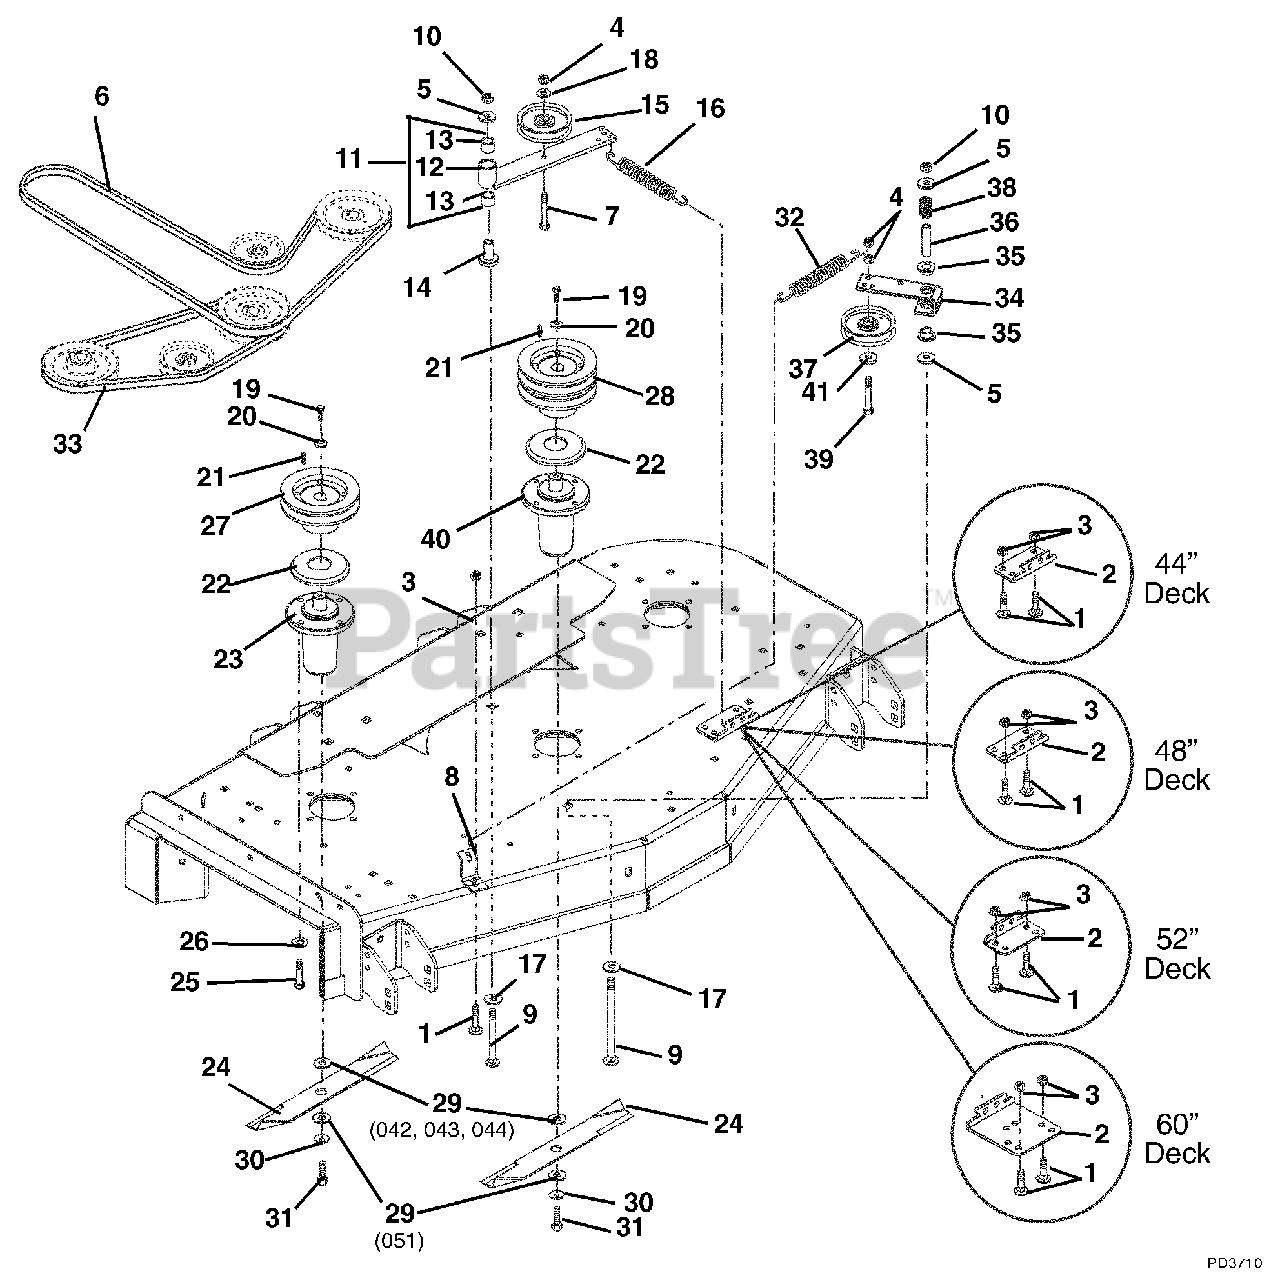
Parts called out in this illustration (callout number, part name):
1	Bolt-Round Head Square Neck .38-16 x .75 Grade 5 (042, 043, 044, 054, 310, 311)
1	Bolt-Round Head Square Neck .38-16 x 1.25 Grade 2 (051, 055)
2	Bracket, Spring (042, 043, 044, 054 310, 311)
2	Bracket, Spring (051, 055)
3	Nut-Locking-Top-Flange .38-16
4	Nut-Locking-Center .38-16
5	Washer-Flat-Steel .531 x 1.25 x .10
6	V-Belt B-Section 51.50 x .625 (042, 044, 054, 310)
6	V-Belt, B-Section 48.80 x .625 (043, 311)
6	V-Belt, B-Section 55.75 x .625 (051, 055)
7	Bolt-Hex .38-16 x 2.75 Grade 5
8	Anchor, Spring
9	Bolt-Round Head Square Neck .50-13 x 3.50 Grade 5
10	Nut-Locking-Top-Flange .50-13
11	Assembly, Idler Pivot Arm (Contains Items 12 & 13)
12	Weldment, Idler Pivot Arm
13	Bearing, 1.00 x 1.12 x .75
14	Bearing, Pedestal Powdered Metal
15	Idler-Flat 4.00 x .38 (2.00 W)
16	Spring-External .09 x 1.00 x 6.00
17	Washer-Flat-Steel .755 x 1.375 x .062 (042, 043, 044, 054, 055, 310, 311)
18	Washer-Flat-Steel .375 x 1.125 x .065
19	Bolt-Hex .38-16 x 1.00 Grade 8
20	Washer-Cupped-Serrated .375
21	Key-Straight .25 x 1.00 x .25
22	Slinger-Dust
23	Assembly, Maintenance Free Spindle
24	Blade- Mower (042, 043)
24	Blade, 32" (16.25) (310, 311)
24	Blade- Mower (18.00) (044, 054)
24	Blade, Mower 60" (051, 055)
24	Blade- Mulching (042, 043)
24	Blade- Mulching (18.00) (044, 054)
24	Blade, Mower 60" Tungsten Mulch (051, 055)
25	Bolt-Hex .38-16 x 1.00 Grade 5
26	Washer-Locking .38 x .094 Regular
27	Weldment, Spindle Sheave 5.00 (042, 043, 044, 054, 310, 311)
27	Weldment, Spindle Sheave 6.00 (051, 055)
28	Sheave, Double (5.25) (042, 043, 044, 054, 310, 311)
28	Sheave, Double (6.25") (051, 055)
29	Washer, Flat .64 x 1.81 x .250
30	Washer-Bellville .63 x 1.625 x .14
31	Bolt-Hex .62-18 x 1.75 Grade 8
32	Spring, Extension
33	V-Belt 5L-Section 49.97 x .672 (042, 043, 310, 311)
33	V-Belt B-Section 19.10 x .672 (044, 054)
33	V-Belt B-Section 23.94 x .625 (051, 055)
34	Arm, Idler Pivot
35	Bushing-Flange .762 x 1.00 x .58 x 1.48 Nylon
36	Spacer .56 x .75 x 2.44 Steel
37	V-Idler, 4.00 x .38
38	Spring-Compression .085 x .80 x 1.00
39	Bolt-Hex .38-16 x 2.25 Grade 5
40	Spindle Assembly (Center)
41	Washer-Flat-Steel .406 x .812 x .065
